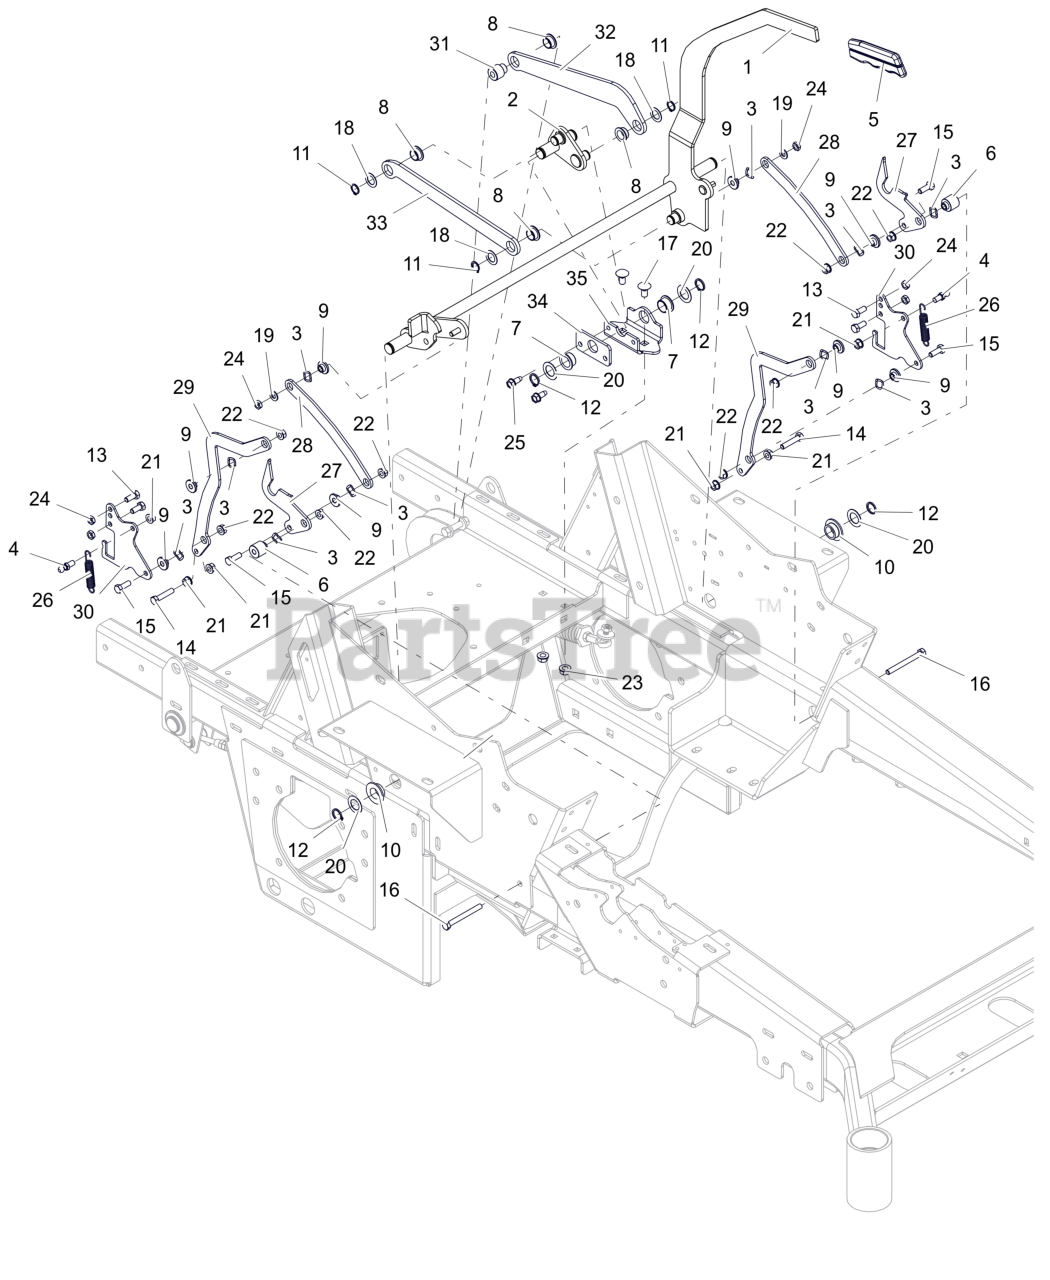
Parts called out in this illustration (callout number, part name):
1	WLDMT, PARKING BRAKE ARM (BLACK)
2	WLDMT, BRAKE ACTIVATION PIVOT
3	WAVE WASHER .531X.781X.125FH
4	STUD- BALL
5	GRIP, PARKING (GRAY)
6	BUSHING FLANGED - .318X.500X.972X.875
7	BSHG, FLANGE .750 X .875 X .5000 X 1.125
8	BSHG, FLANGE .625 X .750 X .375 X 1.000
9	BSHG-FLG .32X.500X.344X.880
10	BSHG-FLG .762X1.48X.44 NYL
11	RG-RTNG-EXT .625X.050
12	RG-RTNG-EXT .689X.078
13	BLT,HEX .31-18X.75 G5 ZCC
14	BLT, HEX .31-18X1.50 G5 ZCC
15	BLT, HEX .31-18X.875 G5 ZCC
16	BLT, HEX .31-18X3.00 G5 ZCC
17	BLT, RHSN .38-16X.750 G5 ZCC
18	WSHR-THRST .625 X 1.0 X .03
19	WSHR,FLT .344X.688X.065 ZCC
20	WSHR-HDND-THRST .758X1.23X.031
21	NUT,SPNLK-FLG .31-18 G5 ZCC
22	NUT,LK-CTR-FLG .31-18 GF ZCC
23	NUT-LK-CTR-FLG .375-16 GF ZCC
24	NUT-LK-CTR-JAM .312-18 GB ZCC
25	SCR,TAP .312-18X.75 HWH TR ZCC
26	SPRING,EXT,.061X.50X3.0
27	BRKT, BRAKE - RTN (BLACK)
28	BRKT, LINK - BREAK RTN (BLACK)
29	BRKT, LINK - SPEED CONTROL HTG
30	BRKT, SPEED - HTG (BLACK)
32	LINK, BRAKE ACTIVATION REAR
33	LINK, BRAKE ACTIVATING FRONT
34	PLATE, BSHG MOUNTING
35	BRKT, BSHG MTG
